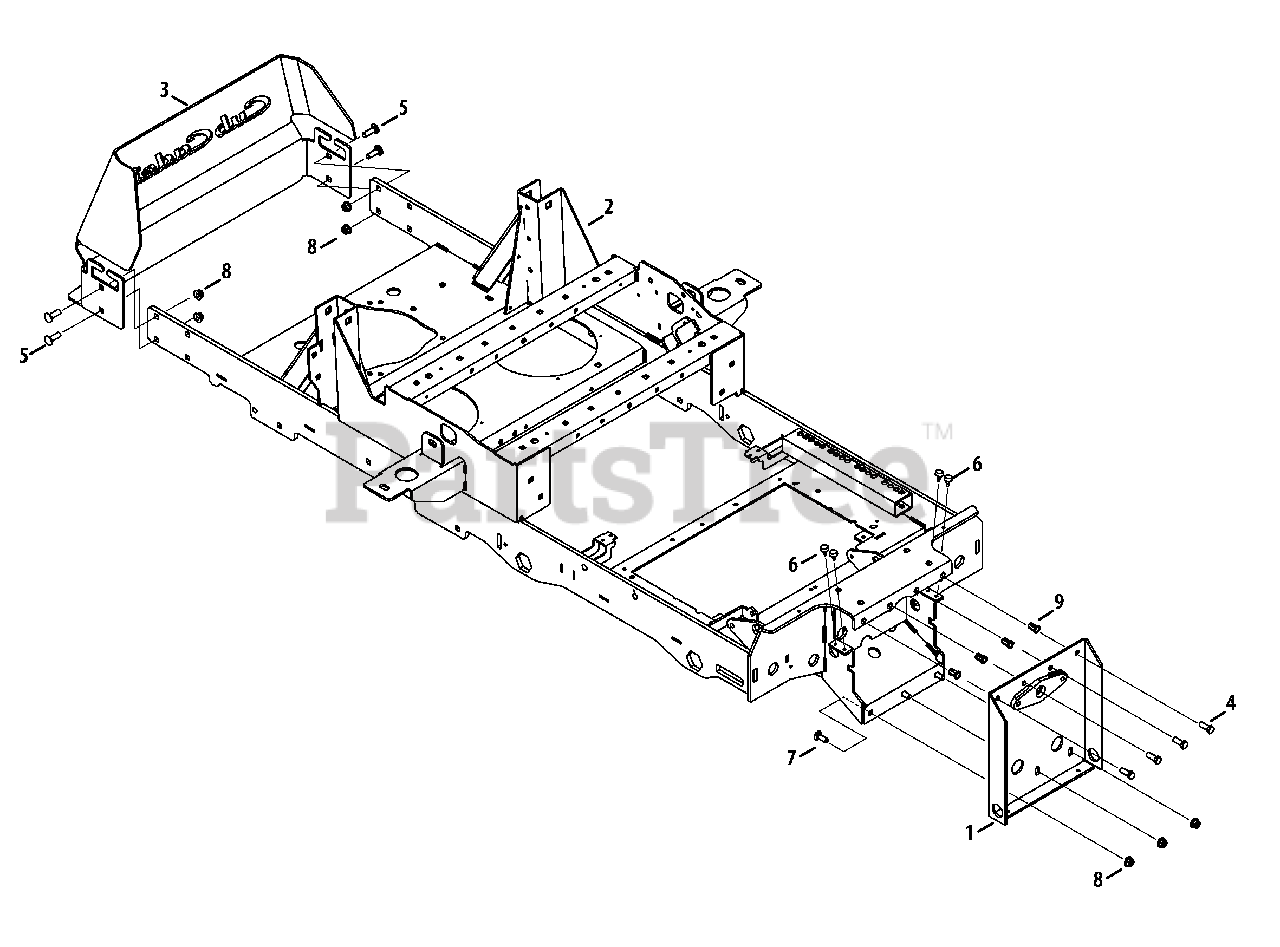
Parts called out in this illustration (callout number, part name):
1	Front Axle Bracket Assembly
2	Frame Assembly
4	Hex Cap Screw, 3/8-16 x 1.00
5	Carriage Bolt, 3/8-16 x 1.25
6	Bumper, .62 Dia. x .3
7	Carriage Bolt, 3/8-16 x 1.00
8	Nylock Nut, 3/8-16
9	Rivet Nut, 3/8-16
